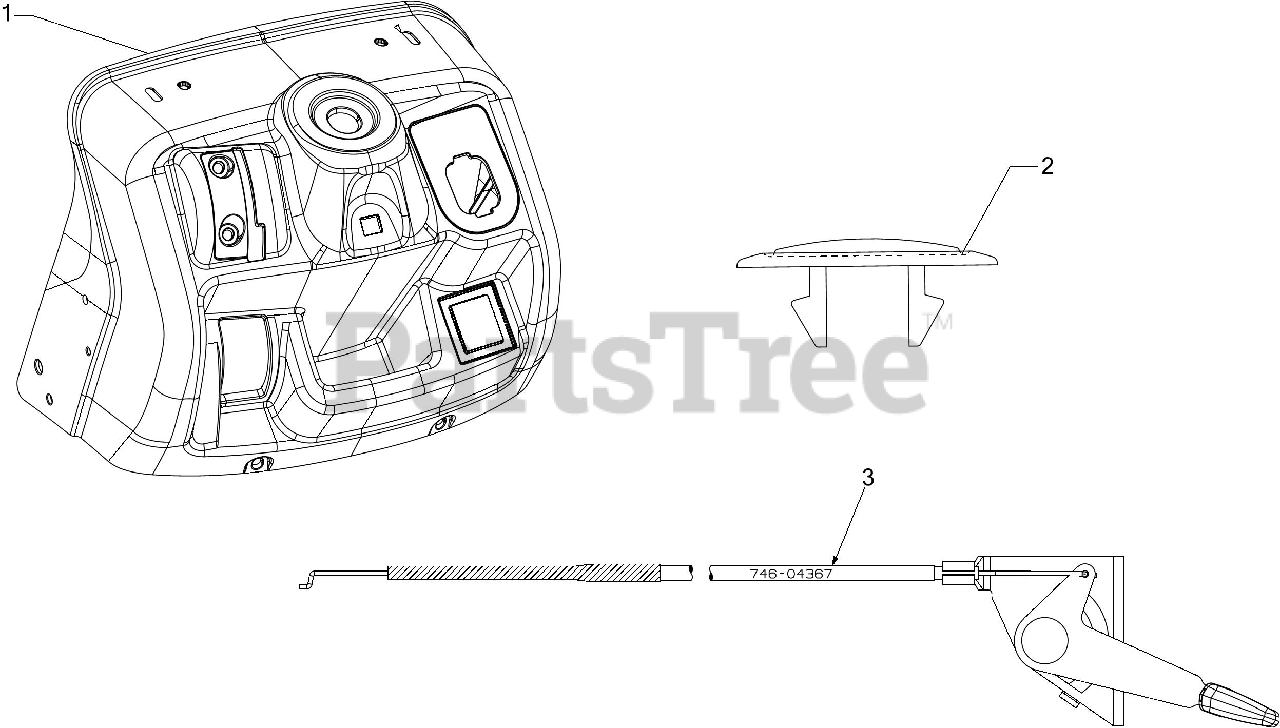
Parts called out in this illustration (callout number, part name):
1	UPPER DASH
2	CHOKE PLUG
3	THROTTLE CABLE 28" x 1.1
